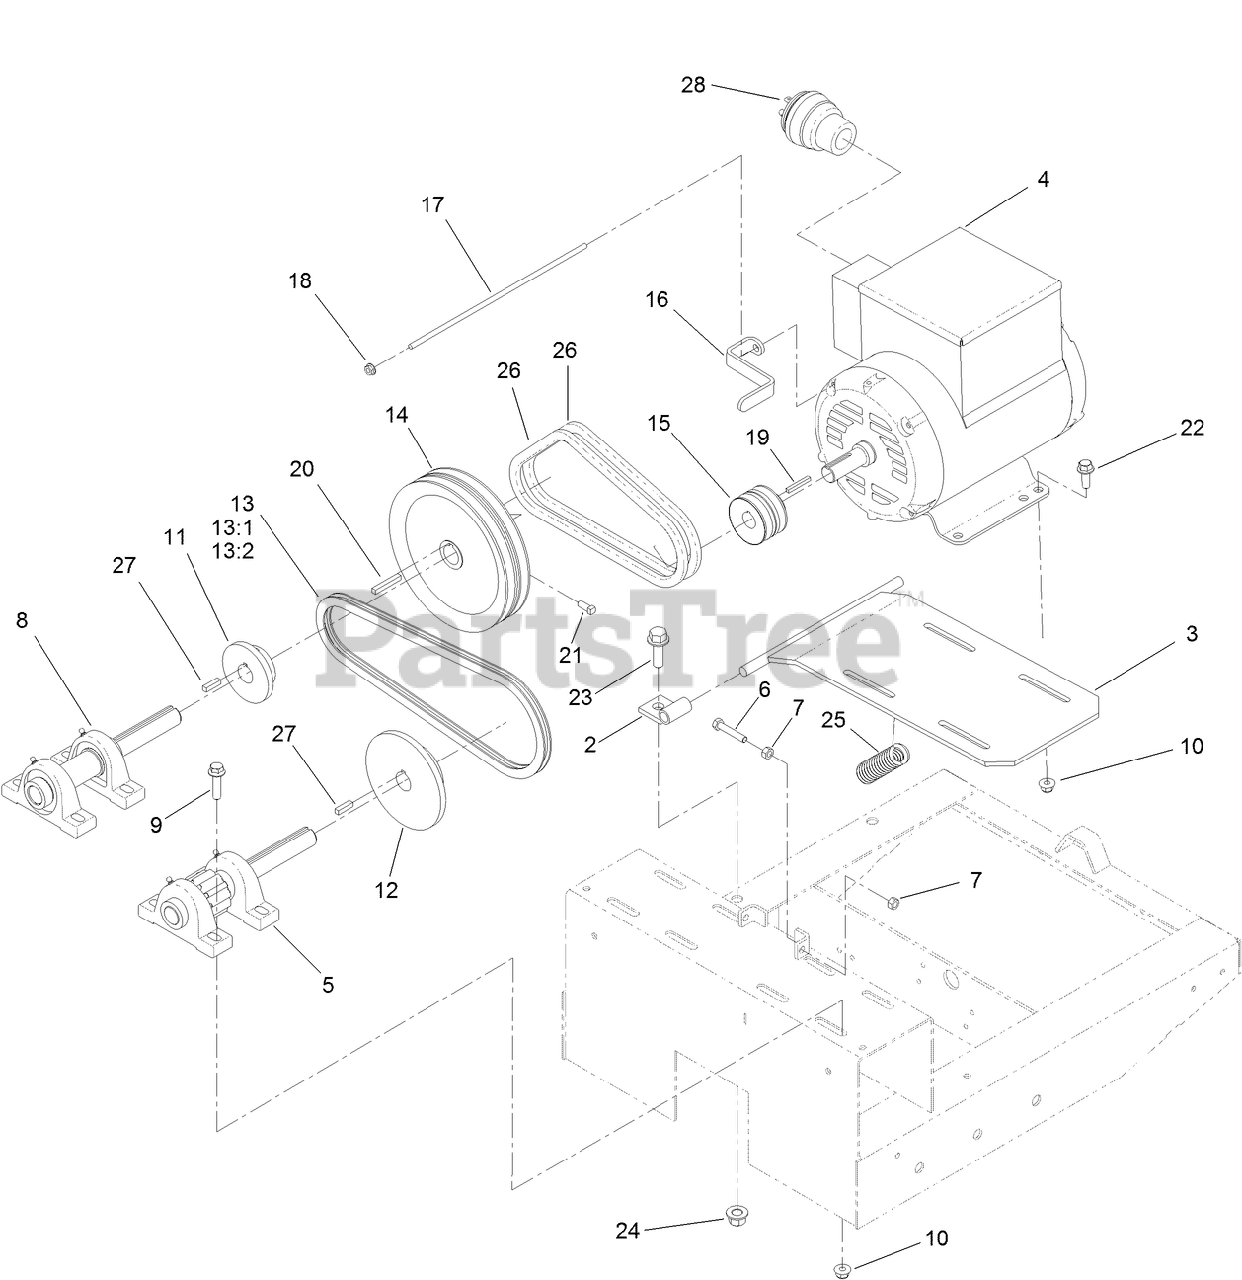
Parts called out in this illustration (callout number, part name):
2	MOUNT-MOTOR
3	BASE-MOTOR
4	MOTOR-ELECTRIC
5	PINION ASM
6	SCREW-HH
7	NUT-HEX
8	IDLER ASM
9	SCREW-HHF
10	NUT-HF, NI
11	SPROCKET
12	SPROCKET
13	CHAIN SET, 53 PITCH
13:1	LINK-OFFSET, NO. 50
13:2	LINK-CONNECTING, NO. 50
14	SHEAVE
15	SHEAVE
16	GUIDE-BELT
17	ROD-THREADED
18	NUT-HF
19	KEY-SQUARE
20	KEY-SQUARE
21	SCREW-SET, SQH
22	SCREW-HHF
23	SCREW-HHF
24	NUT-LOCK
25	SPRING
26	BELT-V
